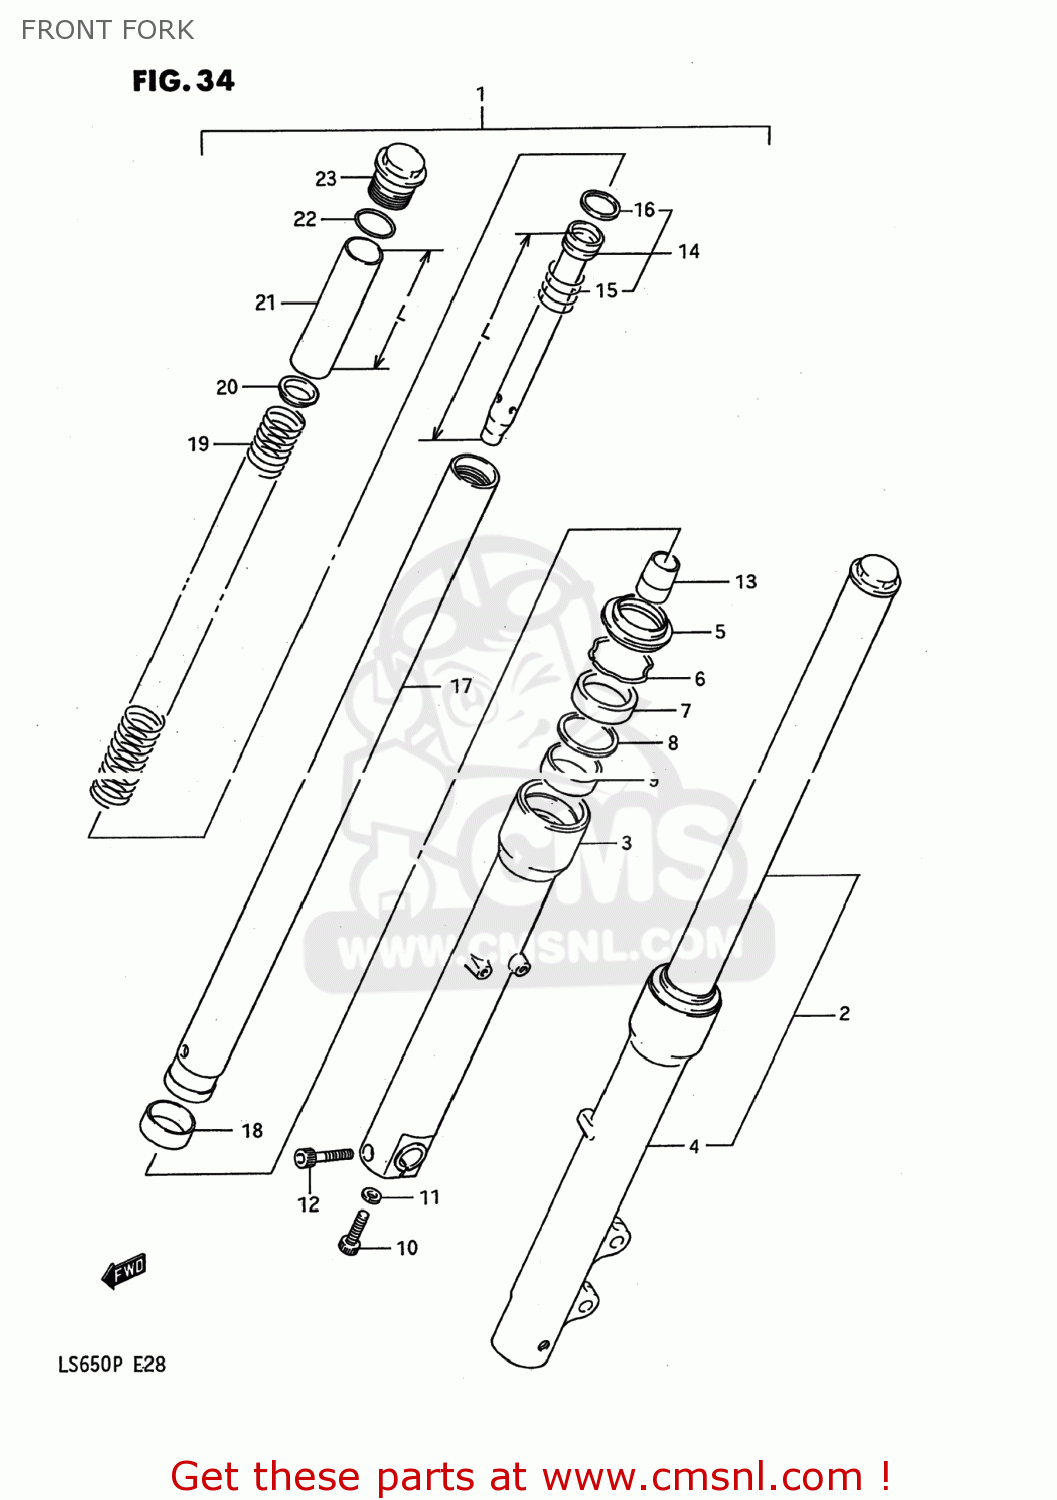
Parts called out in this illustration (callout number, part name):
1	DAMPER ASSEMBLY,RIGHT
2	DAMPER ASSEMBLY,LEFT
3	TUBE,OUTER,R
4	TUBE,OUTER,L
5	SEAL,DUST
6	RING,STOPPER
7	SEAL,OIL
8	WASHER(40X50X2.3)
9	METAL,SLIDE
10	BOLT,FORK CYLINDER(10X25)
11	GASKET (NAS)
12	BOLT
13	PIECE,OIL LOCK
14	CYLINDER
15	SPRING,REBOUND
16	RING,PISTON
17	TUBE,INNER
18	PISTON
19	SPRING
20	GUIDE,SPRING
21	SPACER
22	O RING
23	CAP
